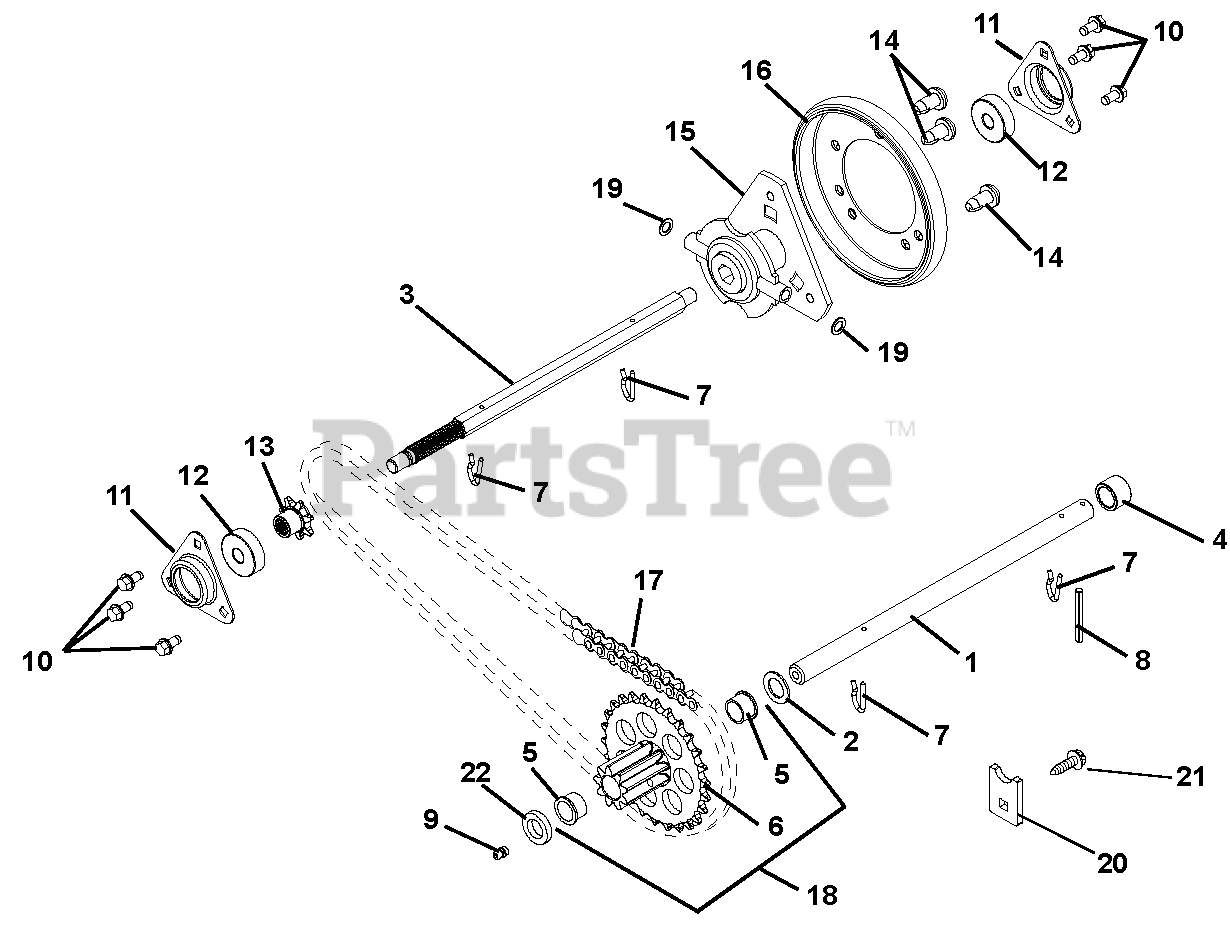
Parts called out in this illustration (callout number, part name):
1	Shaft, Pinion
2	Washer, Flat Steel .630 x 1.005 x .062
3	Shaft, Hex with Spline
4	Spacer .635 x .880 x .611
5	Bushing, Flange .625 x .750 x .500 x .875
6	Pinion and Sprocket
7	Pin, Spring Clip
8	Pin, Roll .125 x 1.00
9	Zerk, Fitting .25 x .125 Drive-In
10	Screw, Tapping Hex Washer Head .25-20 x .50
11	Flange, Bearing
12	Bearing, Ball .437 x 1.375 x .437
13	Sprocket, Pinion 7T with Spline
14	Screw, Serrated Head Tapping .31-18 x .50
15	Carrier, Drive Disk
16	Friction, Disk
17	Chain, #41, 32 Pitches
18	Pinion and Sprocket with Bushings
19	Washer, Flat-Steel .505 x 1.00 x .062
20	Tab, Antirotation
21	Screw, Tapping .25-20 x .50
22	Bushing, Sleeve, .635 x .880 x .305
